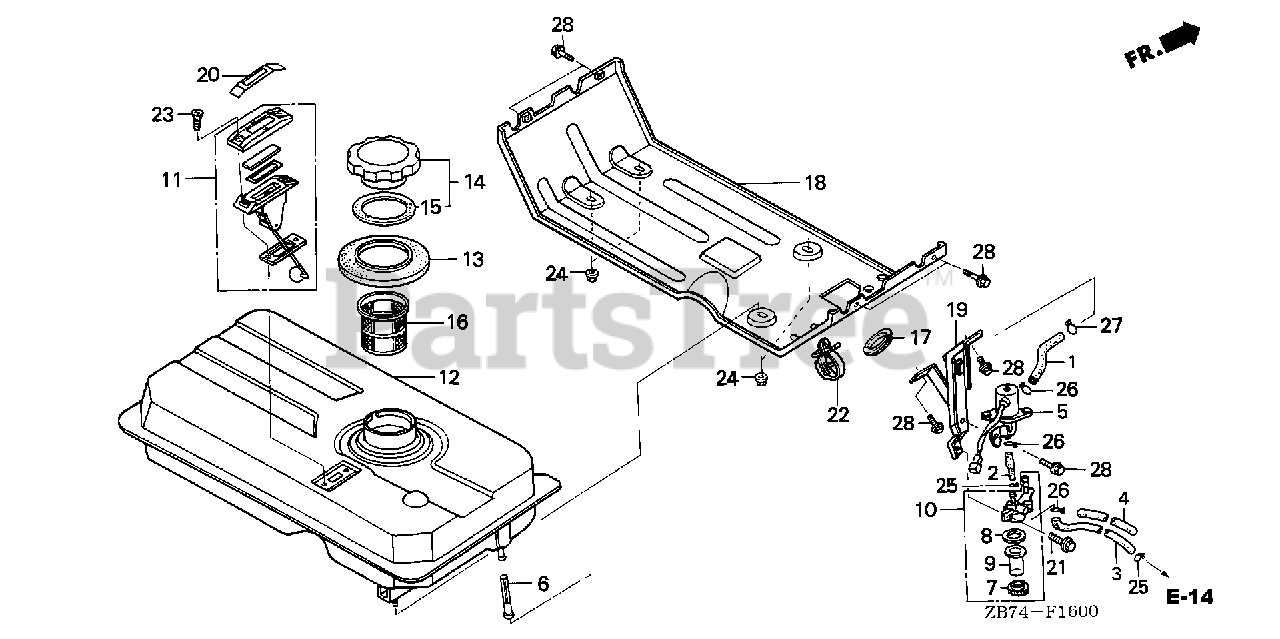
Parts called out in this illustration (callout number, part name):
1	TUBE, FUEL (TANK-VALVE)
2	TUBE, FUEL (VALVE-STRAINER)
3	TUBE, FUEL (STRAINER-CARBURETOR)
4	TUBE, FUEL SUPPORTER
5	PETCOCK ASSY., ELECTRIC FUEL
6	FILTER, FUEL
8	GASKET
9	CUP,FUEL STRAINER
9	CUP, FUEL STRAINER
10	CUP ASSY., FUEL STRAINER
11	METER ASSY., FUEL
12	TANK, FUEL
13	SEAL, FUEL FILLER NECK
14	CAP, FUEL FILLER
15	GASKET, FUEL FILLER CAP
16	FILTER, FUEL
17	GROMMET, WIRE
18	PLATE, FUEL TANK HANGER
19	BRACKET, STRAINER CUP SETTING
20	PLATE, FUEL INDICATION
21	BOLT, FLANGE (5X12)
22	CLIP, WIRE HARNESS
23	SCREW, FLAT (5X10)
24	NUT, FLANGE (6MM)
25	CLIP, TUBE (B8)
26	CLIP, TUBE (B10)
27	CLIP, TUBE (B12) Use from Engine SN 2086984.
28	BOLT, FLANGE (6X12) Use up to Engine SN 1543277.
